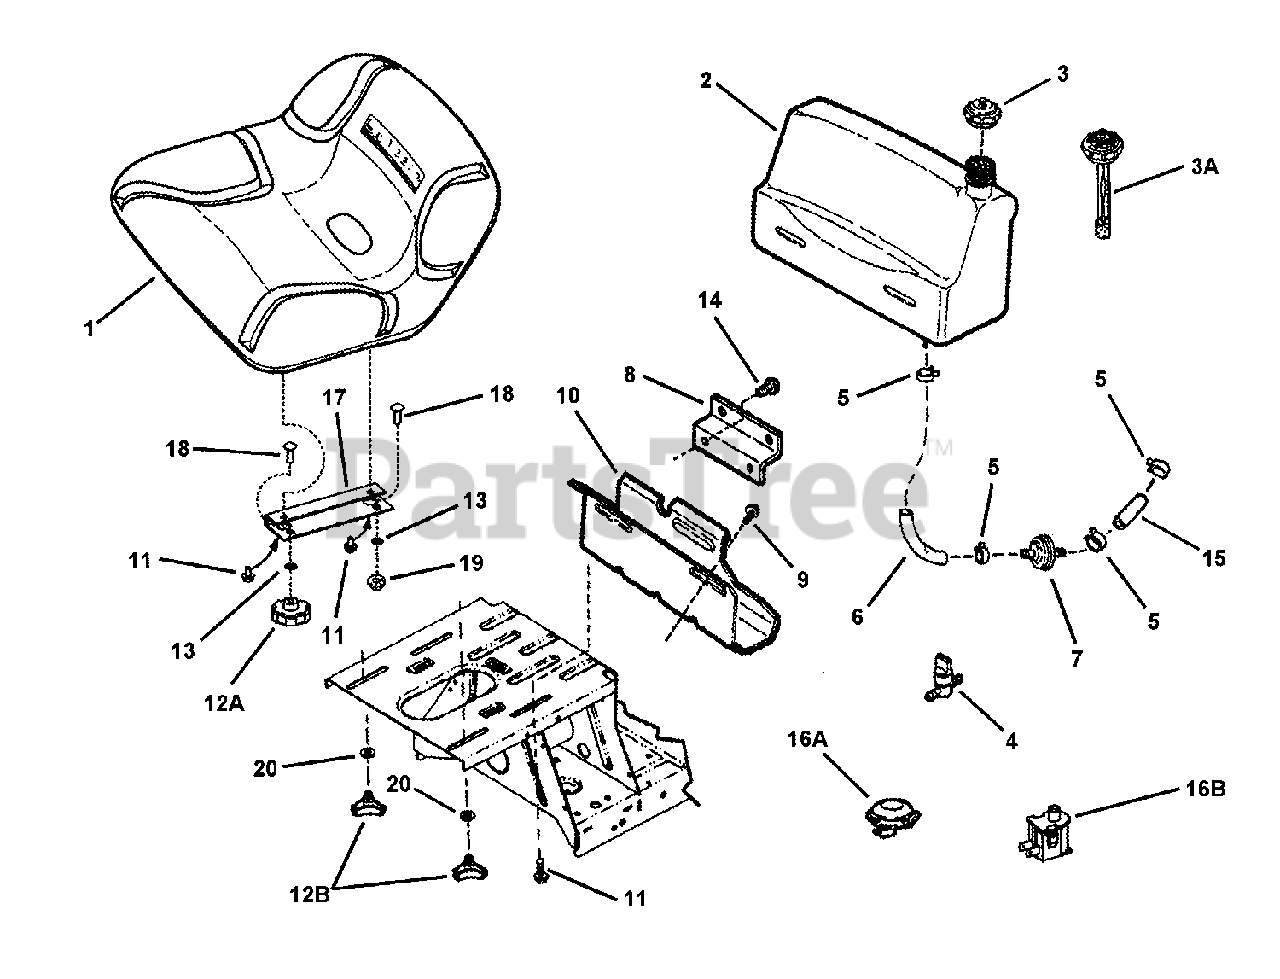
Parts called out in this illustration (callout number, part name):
1	SEAT, V2400 w/slotted Switch Hole
2	ASSEMBLY, Fuel Tank (Includes item 3)
3	CAP, Fuel Tank
3A	CAP, Fuel Tank w/Gauge
4	VALVE, Fuel Shut-Off (Accessory)
5	CLAMP, Fuel Line
6	HOSE, Fuel (1/4" I.D. x 8-1/2" long)
7	FILTER, Fuel (In-Line)
8	BRACKET, Tank, Tall (for Briggs 16HP)
9	SCREW, 5/16-18 x 1/2" Pan Head Self-Tap (Torx #T-40)
10	BRACKET, Fuel Tank (Rear)
11	BOLT, 5/16-18 x 1/2" Hex Flange Nyloc
12A	KNOB, Seat Adjusting, 5/16-18 thread
12B	KNOB, Seat Adjusting (5/16-18 thread)
13	RETAINER, 5/16" Bolt
14	SCREW, 5/16-18 x 1/2" Hex Washer Self-Tap
15	HOSE, Fuel (5" long)
16A	SWITCH, Seat (NC) (for 3" round hole)
16B	SWITCH, Seat (NC) (for slotted hole)
17	BRACKET, Seat
18	BOLT, 5/16-18 x 1" Square Neck Carriage, GR5 YZ
19	NUT, 5/16-18 Hex Flange Top Lock
20	SPACER, .33 x .63 x .156
